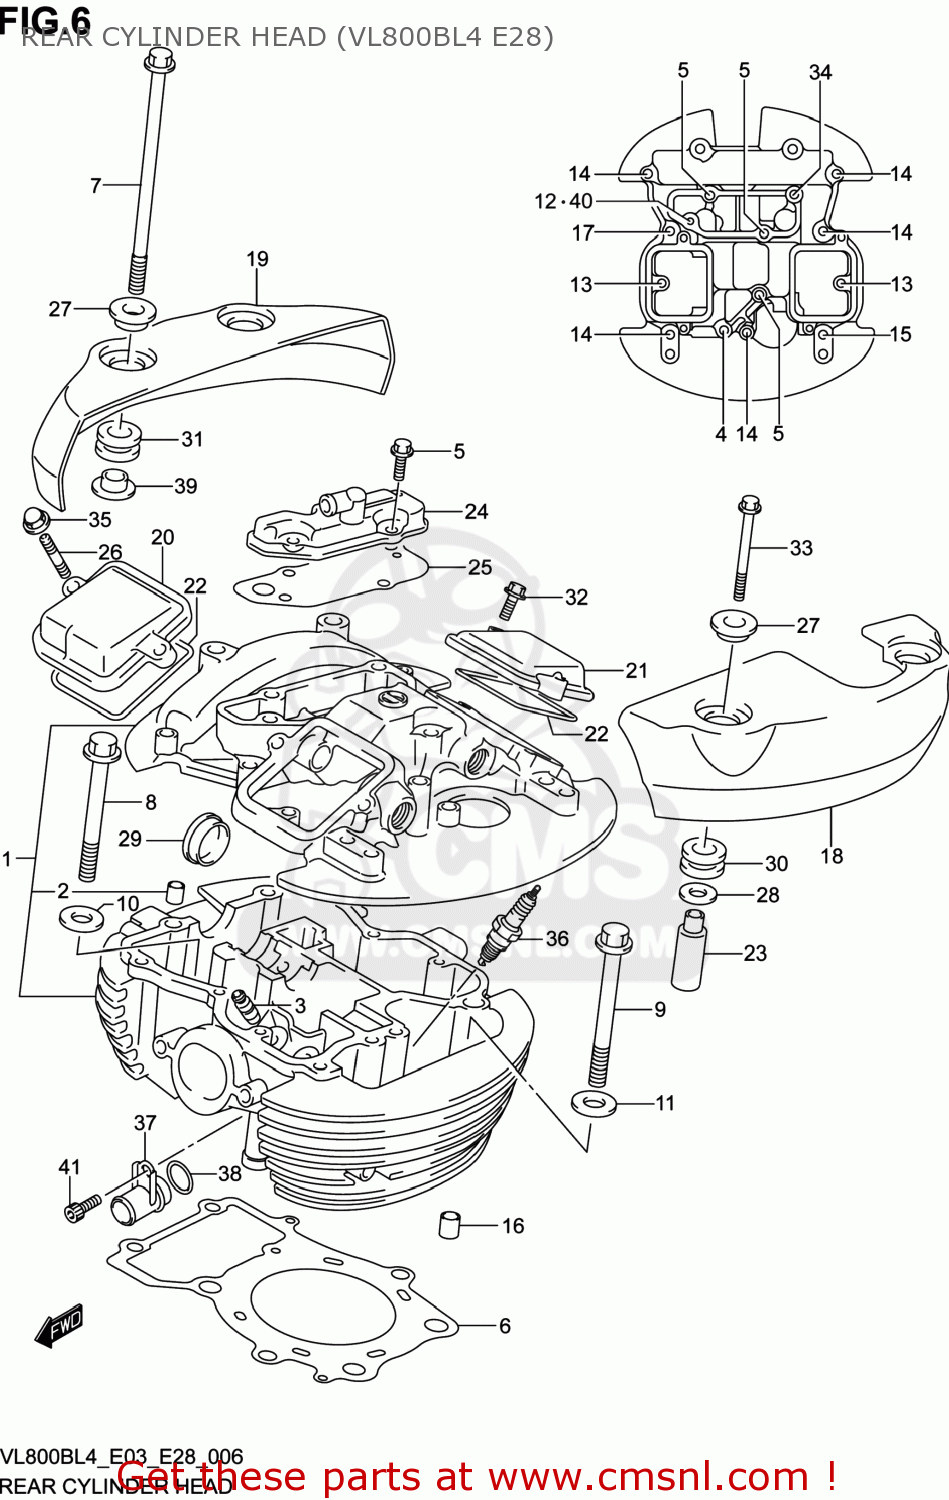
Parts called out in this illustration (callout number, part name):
1	HEAD ASSY,CYLINDER RR
2	PIN(11X14)
3	GUIDE,VALVE(OS:0.3)
4	BOLT(6X50)
5	BOLT(6X55)
6	GASKET,CYLINDER HEAD RR (NAS)
7	BOLT(8X250)
8	BOLT(10X155)
9	BOLT(10X165)
10	WASHER(8.5X24X1.6)
11	WASHER(10.5X22X2.3)
12	BOLT
13	BOLT
14	BOLT
15	BOLT
16	PIN
17	BOLT
18	CAP,CYLINDER HEAD COVER RR,L
19	CAP,CYLINDER HEAD COVER RR
20	CAP,INSPECTION INTAKE
21	CAP,INSPECTION EXHAUST
22	GASKET,INSPECTION CAP (NAS)
23	SPACER,CYL HEAD COVER CAP NO.2
24	COVER,BREATHER
25	GASKET,BREATHER COVER (NAS)
26	BOLT,STUD
27	WASHER(6.5X18X1.6)
28	WASHER(9.5X20X1)
29	PLUG(OD:30)
30	CUSHION
31	CUSHION
32	BOLT
33	BOLT
34	BOLT
35	NUT
36	PLUG,SPARK(DPR7EA-9)
37	UNION,CYL HEAD JOINT
38	O RING(D:2.4,ID:15.8)
39	BUSH
40	GASKET(5.8X13X1.2) (NAS)
41	BOLT
